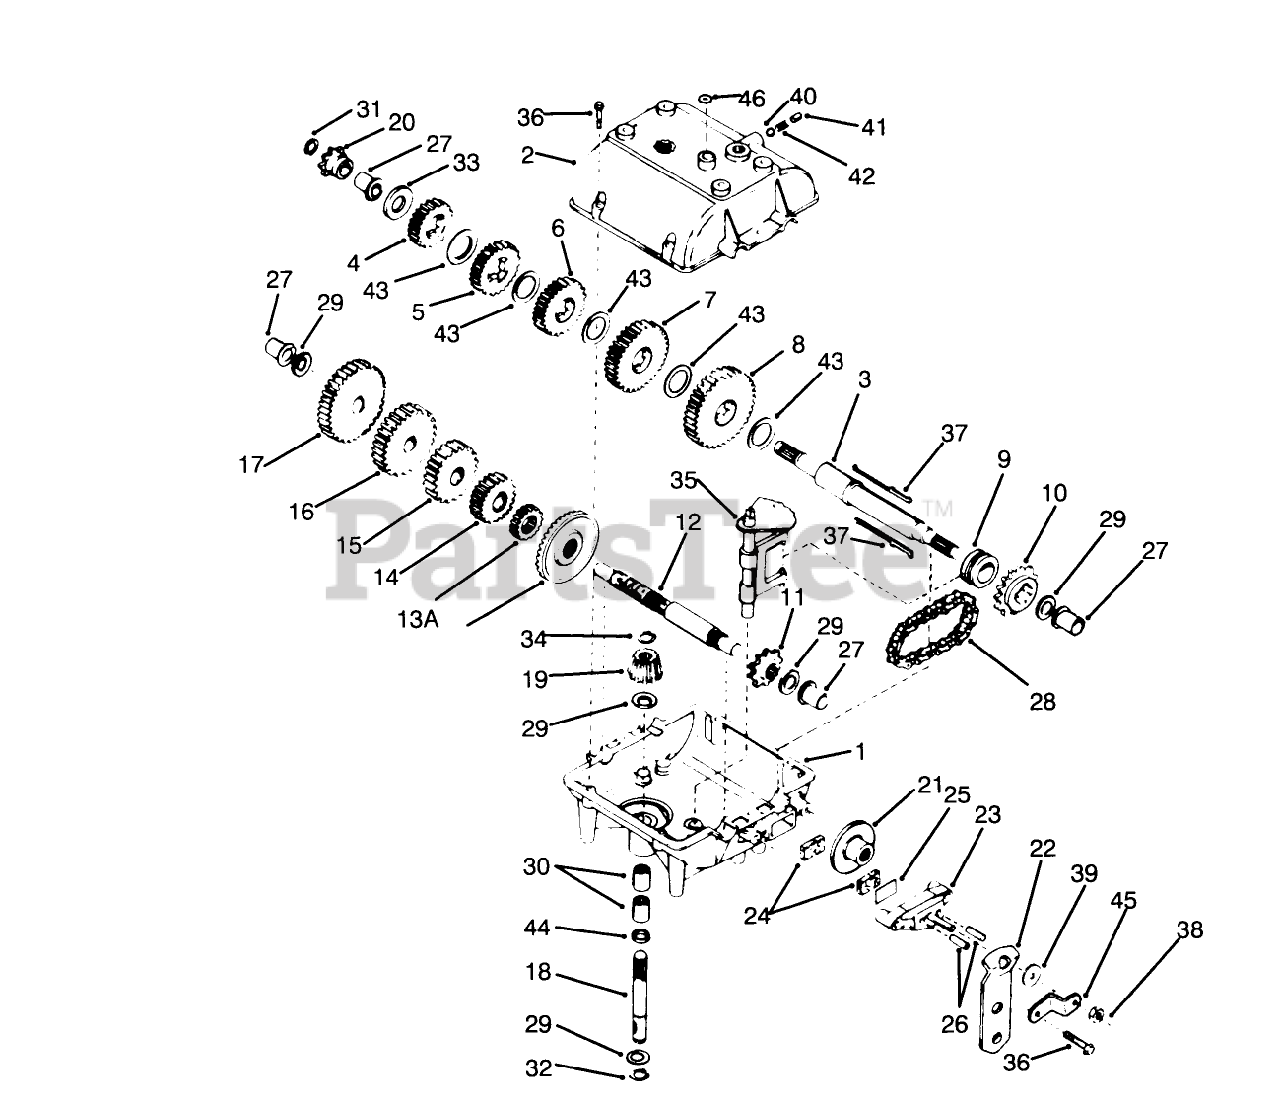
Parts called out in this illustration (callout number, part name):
1	Case-Transmission
2	Cover-Transmission
3	Shaft-Output
4	Gear-Spur 20 teeth
5	Gear-Spur (22 teeth)
6	Gear-Spur, 25 Teeth
7	Gear-Spur, 30 Teeth
8	Gear-Spur, 35 Teeth
9	Collar-Shift
10	Sprocket-18 Teeth
11	Sprocket-9 Teeth
12	Countershaft
13	Gear-Bevel (42 Teeth)
13A	Gear-Spur 15 Teeth
14	Gear-Spur, 20 Teeth
15	Gear-Spur, 25 Teeth
16	Gear-Spur (28 teeth)
17	Gear-Spur (30 teeth)
18	Shaft-Input
19	Bevel Pinion-Input
20	Sprocket (8Teeth)
22	Lever-Brake
23	Nozzle-Carburetor
24	Brake Pad
25	Brake Pad Plate
26	Dowel Pin
27	Bushing-Flange
28	Chain-Roller #41
29	Washer
30	Bearing-Needle
31	Piston Asm (.020 O S)
32	Ring-Snap
33	Washer
34	Ring-Retainer
35	Rod and Fork ASM
36	Ring Set (.020 O S)
38	Locknut
39	Washer
40	Ball-Steel
41	Screw-Set
42	Spring
43	Washer
44	O Ring
45	Bracket
46	Cut Seal-Square
